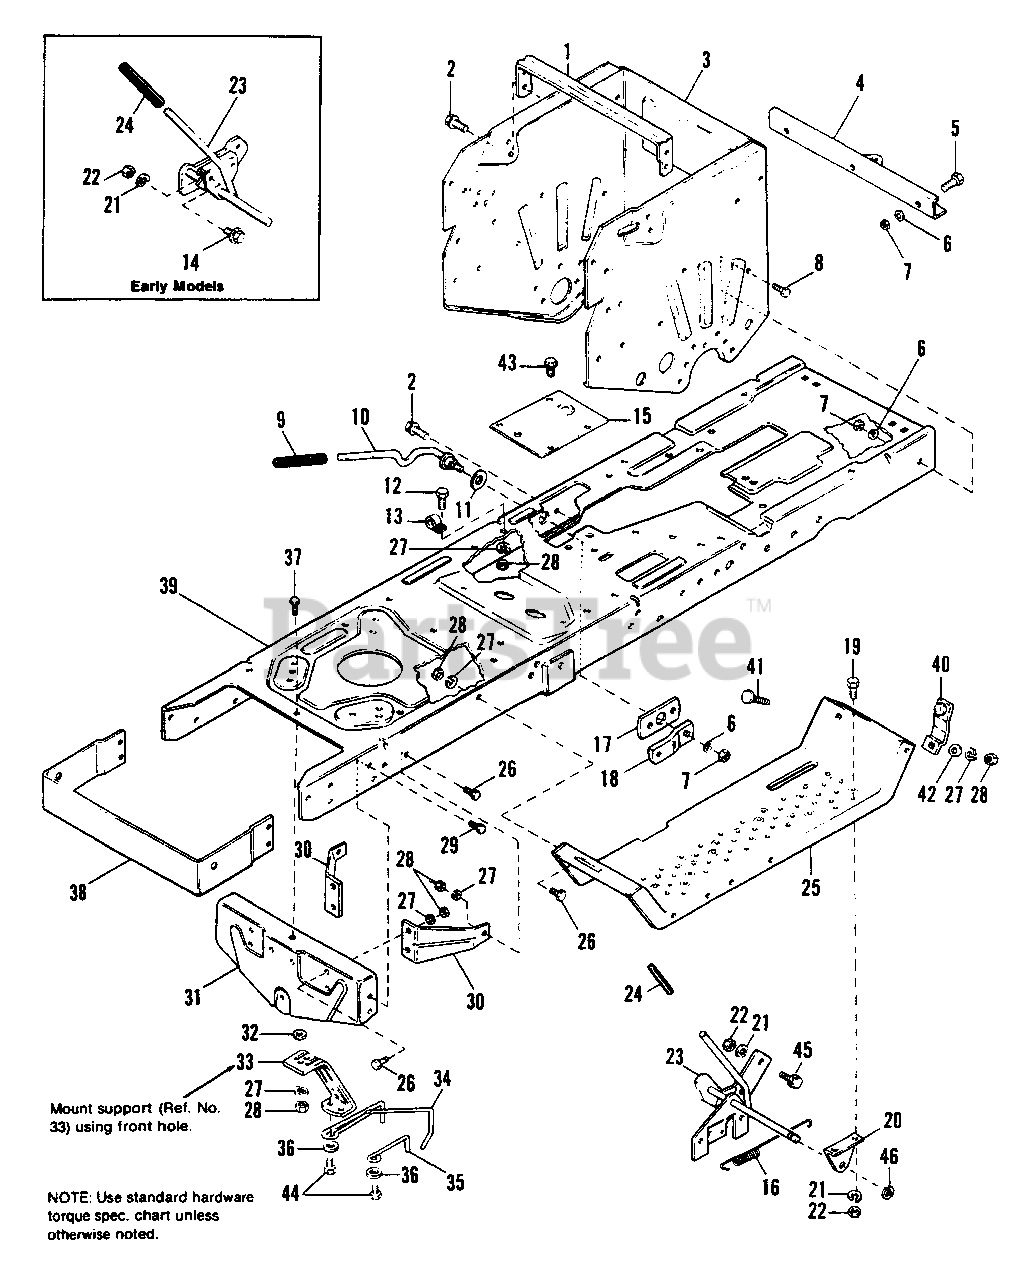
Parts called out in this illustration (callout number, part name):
1	BRACE, Seat
2	SCREW, Taptite, 5/16-18 x 1/2
3	SUPPORT, Axle Wrapper
4	BAR, Draw
5	CAPSCREW, Hex, 3/8-16 x 1
6	LOCKWASHER, 3/8
7	NUT, Hex, 3/8-16
8	CAPSCREW, Hex, 3/8-16 x 3/4
9	GRIP, Handle
10	HANDLE, Lift
12	CAPSCREW, Hex, 5/16-18 x 1-1/4
14	CAPSCREW, Hex Washer Hd., 1/4 20 x 5/8
15	PLATE, Adaptor
16	SPRING, Extension (Used on 1690840 after serial no. 3329 and 1690909 after serial no. 2607.)
17	BAR, Support
18	ARM, Support
19	CAPSCREW, Hex, 1/4-20 x 5/8
20	SUPPORT, Clutch
21	LOCKWASHER, 1/4
22	NUT, Hex, 1/4-20
23	LEVER ASSY., Clutch PTO (Used on 1690840 before serial no. 3330 and on 1690909 before serial no. 2608 and on all 1690843.)
23	LEVER ASSY., Clutch, PTO (Used on 1690840 after serial no. 3329 and on 1690909 after serial no. 2607.)
24	GRIP, Handle
26	CAPSCREW, Hex, 5/16-18 x 3/4
27	LOCKWASHER. 5/16
28	NUT, Hex, 5/16-18
29	SCREW, Taptite, 5/16-18 x 3/4
30	BRACE, Axle Support
31	SUPPORT, Axle
32	WASHER, Plain, 11/32-1 x 10 Ga.
36	WASHER, 1/4
37	CAPSCREW, Hex Hd., 5/16-18 x 1
40	LATCH ASSY.
41	CARRIAGE BOLT, 5/16-18 x 3/4
42	WASHER, Plain, 5/16
43	SCREW, Taptite, 1/4-20 x 1/2
44	CAPSCREW, Hex, 5/16-18 x 7/8
45	SCREW, Taptite, 1/4-20 x 5/8 (Used on 1690840 after serial no. 3329 and 1690909 after serial no. 2607.)
46	RING, Retaining (Used on 1690840 after serial no. 3329 and 1690909 after serial no. 2607.)
